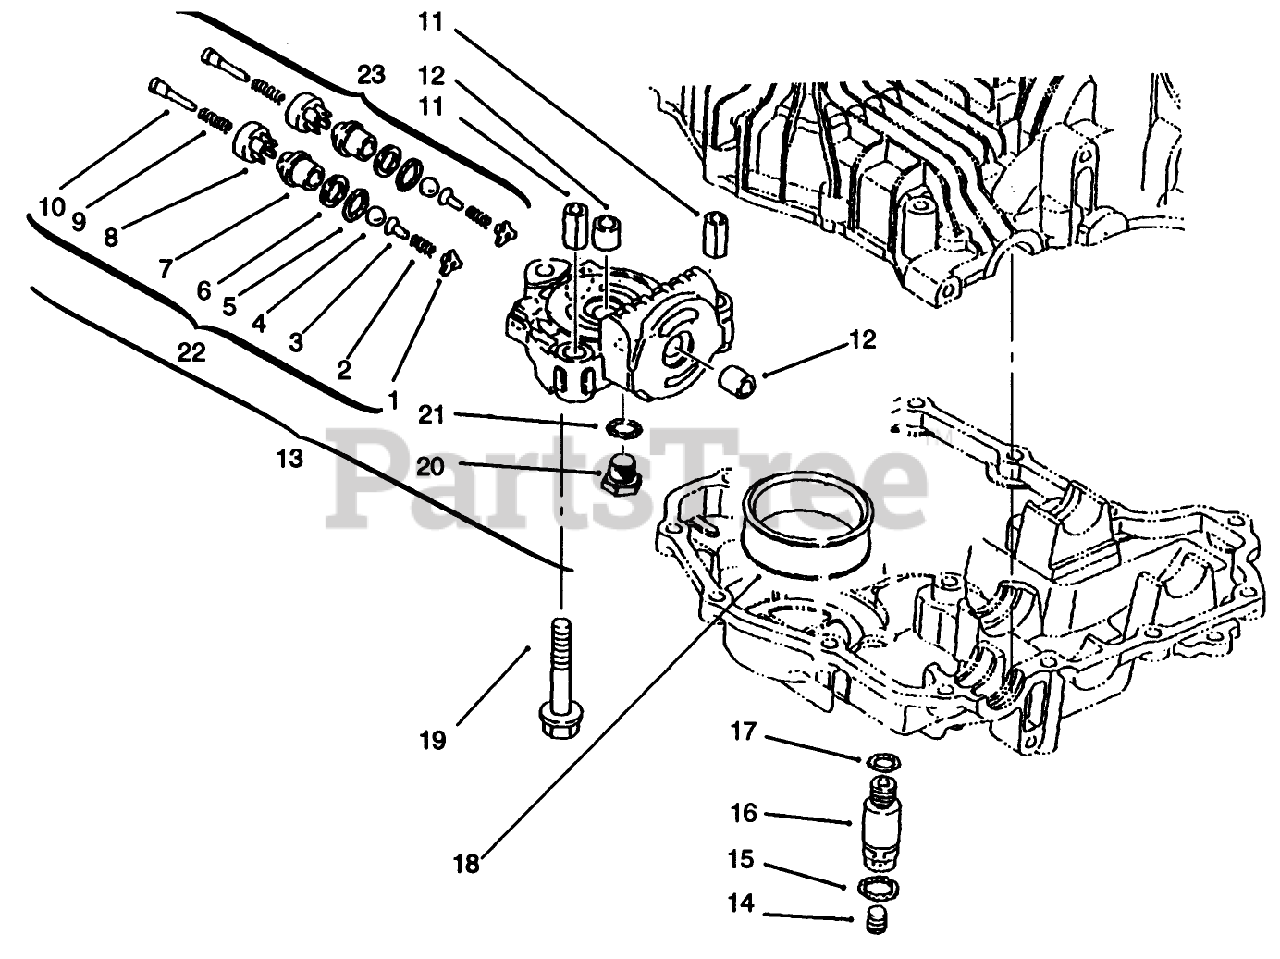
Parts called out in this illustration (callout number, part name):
3	Holder-Ball
4	Ball
6	RING-BACK UP
8	Valve B
10	Pin-Push
11	PIN-KNOCK
12	BUSHING
15	O-RING
16	CONNECTOR
17	PACKING
18	FILTER
21	PACKING
22	ASM - VALVE A1 INC 1-10
23	ASM - VALVE A2
